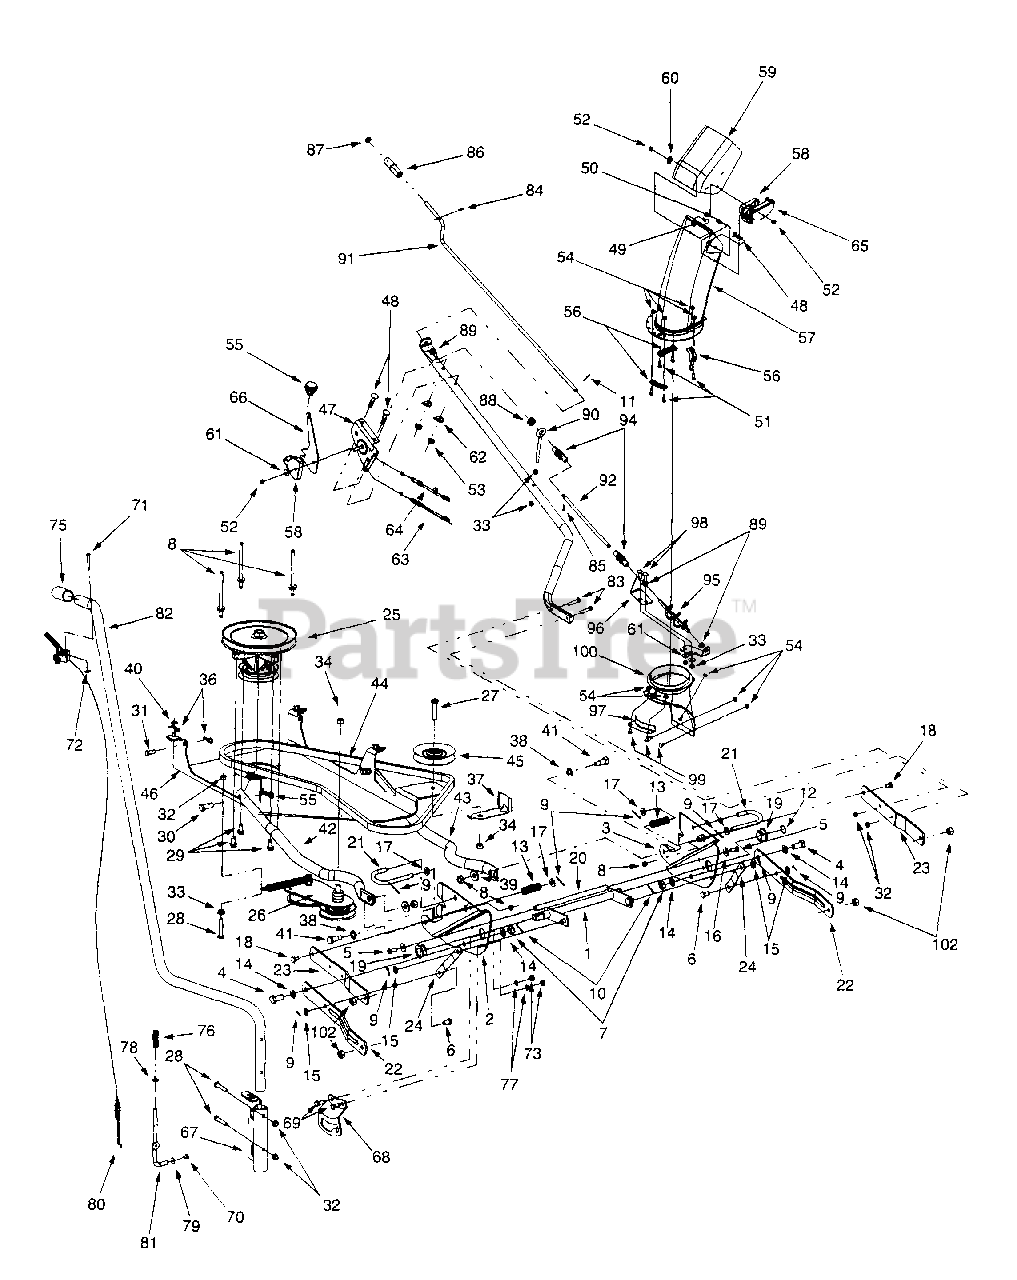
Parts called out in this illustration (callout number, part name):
1	Rod Assembly
4	Hex Cap Screw, 5/8-18 x 1.31
5	Hex Cap Screw, 3/8-16 x 1.0
6	Clevis Pin, .5 x .78
7	Slotted Hex Nut, 5/8-18
8	Belt Keeper Pin
9	Cotter Pin, .125 x .75
10	Cotter Pin, 1/8 x 1.25
11	Cotter Pin
12	Snap Ring
13	Compression Spring, .72 x 2.25
14	Flat Washer, .64 x 1.12 x .125
15	Flat Washer, .51 x 1.0 x .060
16	Bell Washer, .396 x 1.14 x .095
17	Flat Washer, .531 x .875 x .15
18	Shoulder Screw, .5 x .29, 3/8-16
19	Flange Bearing w/ Flats
20	Rod, 1/2 x 11.55
21	Handle Rod
22	Link, 15.3
23	Link, 13.25
25	Spindle Assembly
26	Double-idler Bracket Assembly
27	Hex Cap Screw, 3/8-16 x 1.75
28	Hex Cap Screw, 5/16-18 x 1.75
29	Self Tapping Screw, 5/16-18 x .75
30	Clevis Pin, .5 x 1.18
31	Clevis Pin, 3/8 x .75
32	Flange Lock Nut, 5/16-18
33	Hex Nut, 5/16-18
34	Hex Flange Lock Nut, 3/8-24
36	Click Pin, .092 x 1.64
37	Belt Guard
38	Flat Washer, .531 x .93 x .09
39	Flat Washer, .38 x .93 x .11
40	Flat Washer, .344 x .688 x .065
41	Shoulder Screw, 3/8-16, .5 x .B35,
42	RH Support Tube
43	LH Support Tube
44	Upper V-belt (Tractor's w/ Electric
44	Upper V-belt Tractor's w/ Manual
45	Idler Pulley, 3.5" Diameter
48	Carriage Bolt, 5/16-18 x 1.5
49	Carriage Bolt, 5/16-18 x .75
50	Hex Index Washer Screw, 1/4-14 x
51	Hex Cap Screw, 1/4-20 x.75
52	Nylon Hex Lock Nut, 5/16-18
53	Flange Lock Nut, 5/16-18
54	Hex Flange Lock Nut, 1/4-20
56	Chute Flange Keeper
57	Lower Chute
58	Chute Tilt Cable Guide
59	Upper Chute
60	Flat Washer, .344 x 1.125 x,125
61	Bell Washer, .34 x .872
62	Saddle Washer, .32 x .93
63	Chute Cable, 62"
64	Chute Cable w/ Clip, 62"
66	Chute Tilt Handle
70	Hex Index Washer Screw #10-16 x
71	Pan Phillips Screw, #10-24 x .75
72	Flat Weld Nut, #10-24
73	Hex Nut, 5/16-24
74	Heavy Duty Spirol Pin, 1/4 x 1.5
75	Handle Grip
76	Compression Spring, .406 x .531 x
77	Lock Washer, 5/16
78	Flat Washer, .385 x .62 x .063
79	Flat Washer, .194 x .62 x .063
80	Lift Cable, 42" w/ Trigger Control
81	Lift Index Rod
83	Hex Cap Screw, 5/16-1B x 1.5
84	Rolled Pin, 1/8 x.63
85	Spirol Pin, .125 x .82
86	Crank Knob
87	Push Cap, 3/8 ID
88	Rubber Grommet, .44 x .94 x .5
89	Plastic Bushing
90	Eye Bolt
91	Chute Crank Rod, .375 x 33
92	Rod, .375 x 11.375
93	Support Chute Tube
94	Joint Block Assembly
95	Chute Crank Assembly
98	Splined Carriage Screw, 5/16-18 x 1.0
99	Carriage Screw, 1/4-20 x .5
100	Adapter Chute
101	Chute Crank Bracket
102	Hex Lock Nut, 1/2-13
